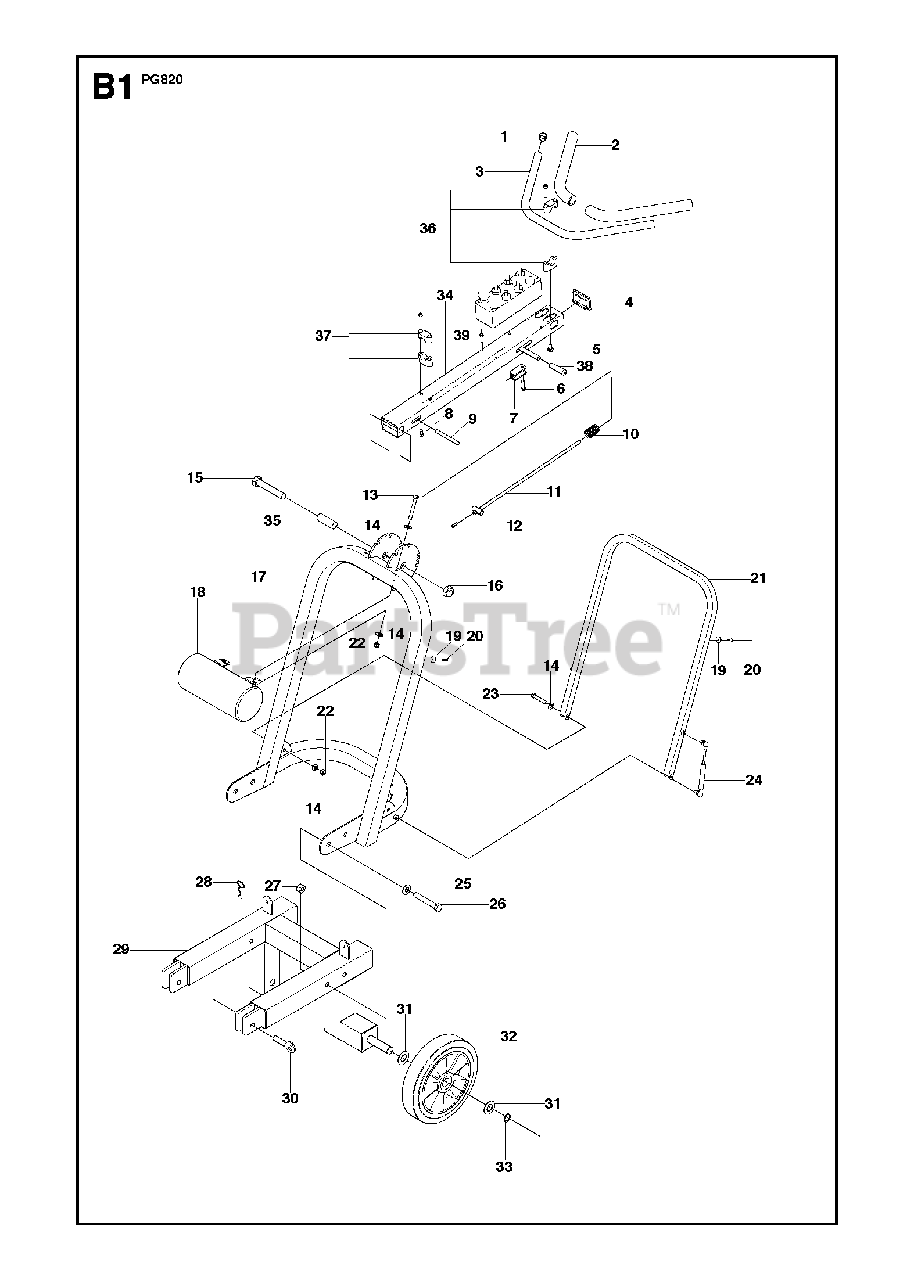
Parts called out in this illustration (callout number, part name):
1	EMBOUT REF 320 GL 25/
14	WASHER
22	HEXAGON LOCKING NUT
28	SPRING COTTER
